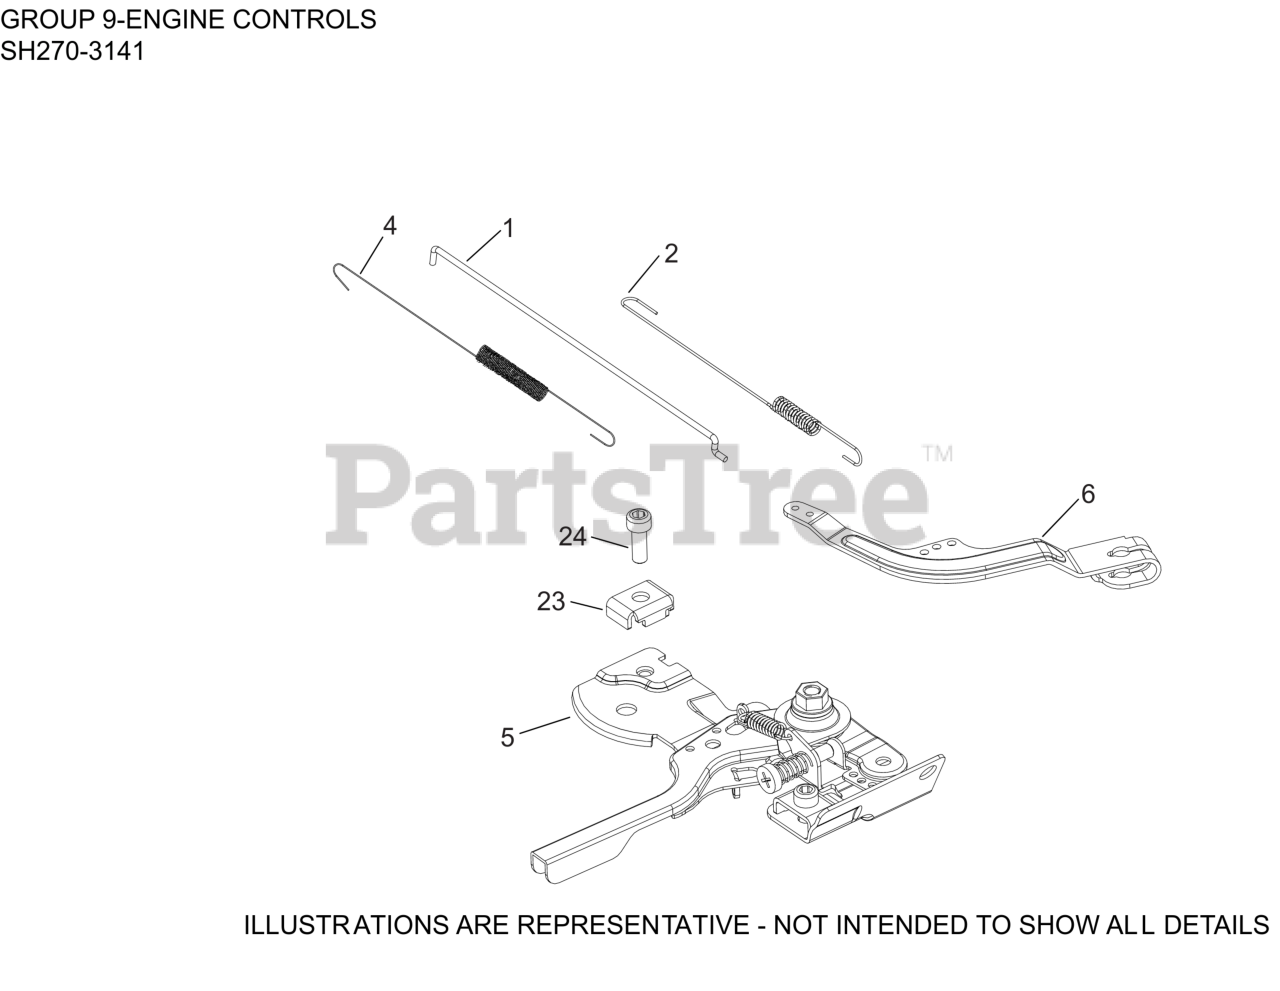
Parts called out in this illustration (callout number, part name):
1	LINKAGE, GOVERNOR-USE 18 079 05-S
2	SPRING, GOVERNOR
4	SPRING, LINKAGE
5	VARIABLE SPD CNTRL ASSY W/O KILL
6	KIT, GOVERNOR LEVER
23	CLAMP, CABLE
